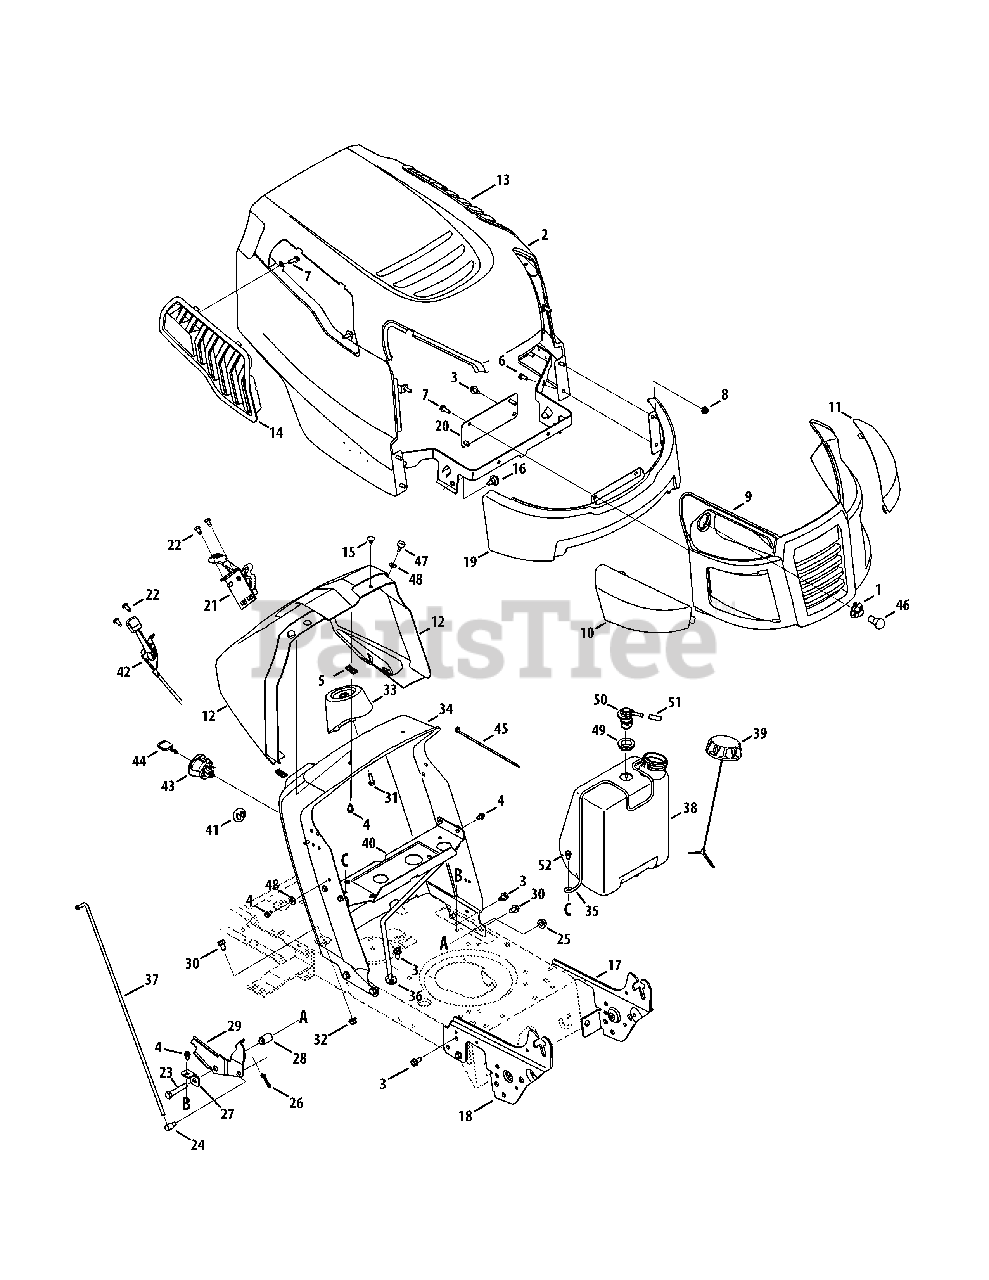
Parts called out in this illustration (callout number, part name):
1	Bulb Socket
2	Hood Assembly
3	Screw, 5/16-18 x .750
4	Hex Washer Screw, 1/4-20 x .500
5	Tin Clip Nut, 1/4-20
6	Hex Screw, 1/4-20 x .620
7	Screw, 1/4 x .750
8	Nut, Hex Flange Insert Lock, 1/4-20
10	Headlight Lens, RH
11	Headlight Lens, LH
12	Dash Collar
13	Hood Scoop, LH
14	Hood Scoop, RH
15	Bumper
16	Shoulder Screw, 5/16-18
17	Left Support Pivot Bracket
18	Right Support Pivot Bracket
19	Lower Grill
20	Lower Grill Bracket
21	Speed Selector, 7-Speed
22	Self-Tap Screw, 1/4-20
23	Hex Head Screw, 3/8-16
24	Ferrule, 1/4-20 x 1.00
25	Nut, Hex Flange Insert Lock, 3/8-16
26	Cotter Pin
27	Speed Latch Support Tab
28	Flange Spacer
29	Speed latch
30	Self-Tap Screw, 5/16-18
31	Hex Screw, 1/4 x .750
32	Nut, Hex Flange Lock, 5/16-18
33	Steering Support
35	Fuel Tank Support Rod
36	Dash support Rod
37	Speed Selector Control Rod
38	1.5 Gallon Fuel Tank
38	1.36 Gallon Fuel Tank
39	Fuel Cap
40	Gas Tank Support Bracket
41	Choke Plug
42	Throttle/Choke Assembly
43	Key Switch Module
44	Key (2 pack)
45	Cable Tie
46	Headlight Bulb
47	Ratchet Clip: .250 x .500
48	Flat Washer, .25 x .630 x .0515
49	Rubber Grommet
50	Fuel Rollover Valve
51	Vent Hose
52	Hex Washer Screw, 1/4-20 x .625
